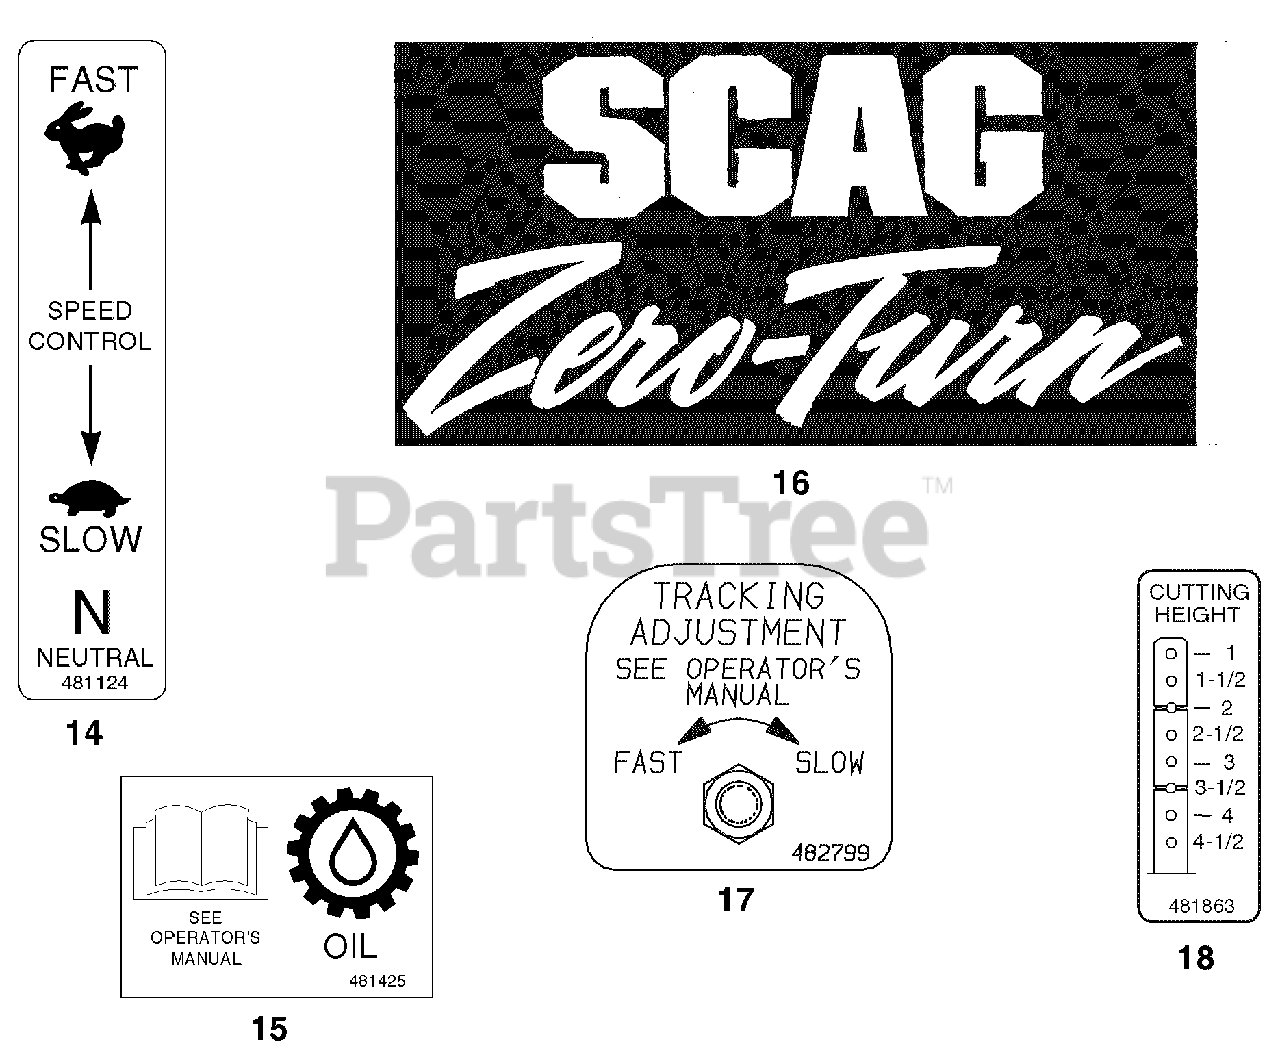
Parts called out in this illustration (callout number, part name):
14	Decal, Speed Control
15	Decal, Oil
16	Decal, Scag Zero Turn
17	Decal, Tracking Adjustment
18	Decal, Cutting Height
